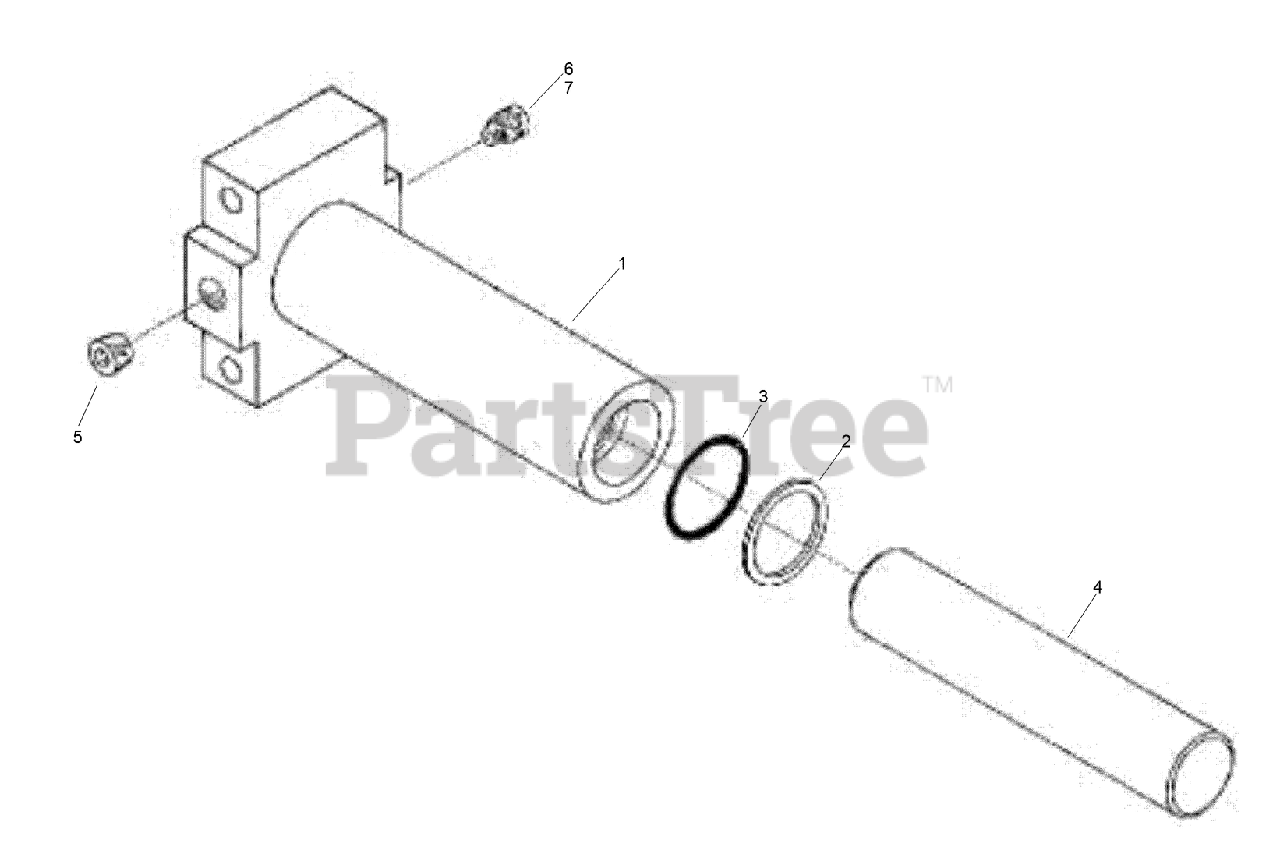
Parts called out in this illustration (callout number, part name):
1	ADJUSTER
2	WASHER-BACKUP
3	O-RING
4	ROD-BOOM, END (CYLINDER)
5	PLUG-BLEED
6	FITTING-LUBE, STRAIGHT
7	Cap
